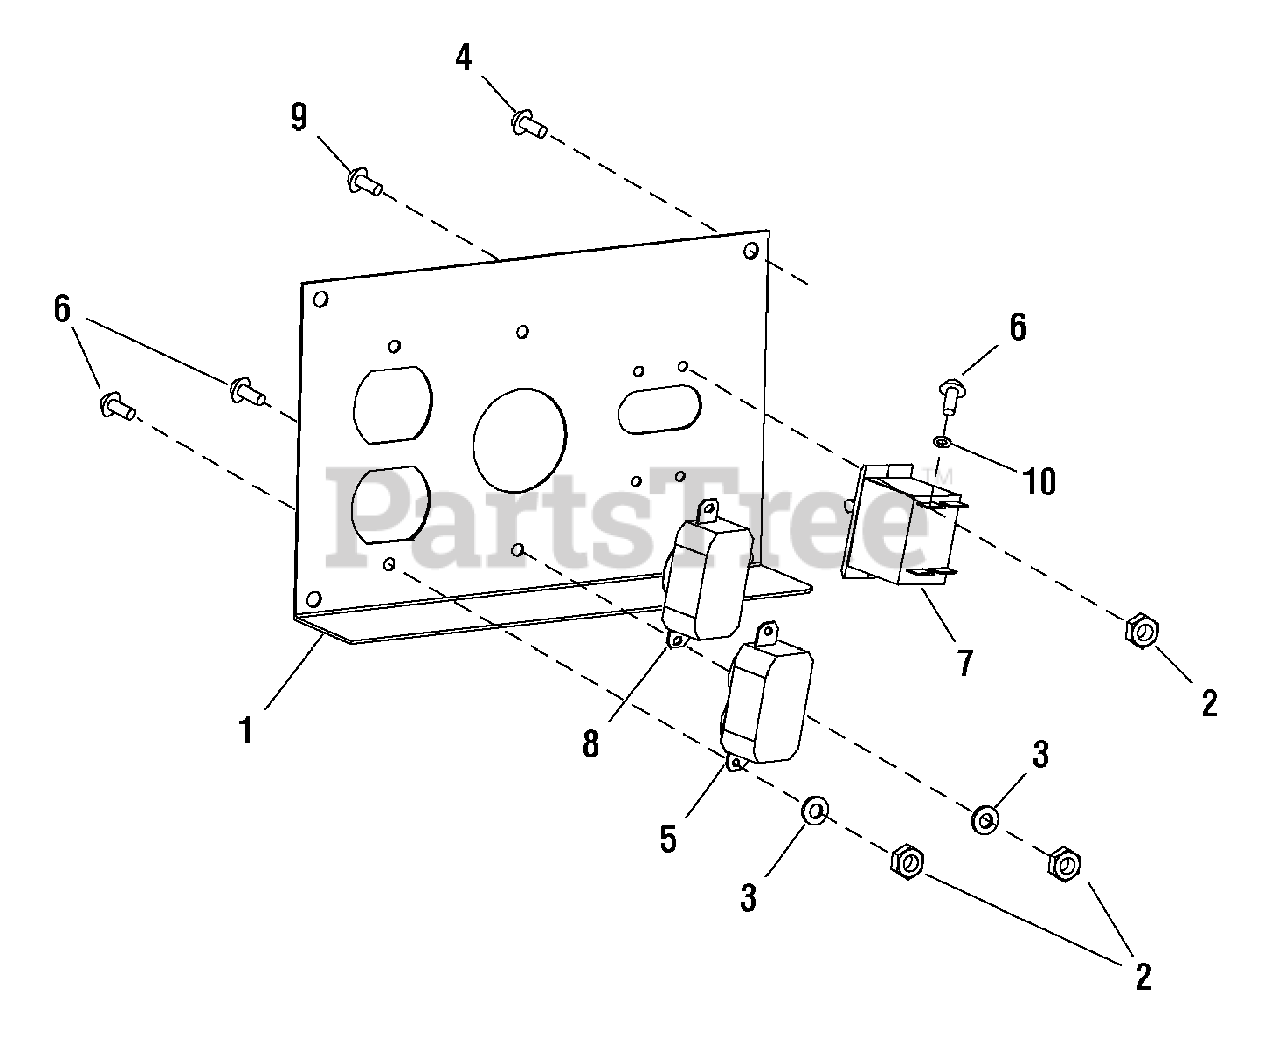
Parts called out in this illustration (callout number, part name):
1	CONTROL PANEL
2	* NUT, Nylon
3	* WASHER, M4 x 08
4	* SCREW, M6 x 16
5	OUTLET, 120/125V, 15/20a, Duplex
6	* SCREW, Pan Head, M4 x 10
7	CIRCUIT BREAKER, 15A
8	OUTLET, 120/240V, 20a, Locking
9	* SCREW, M3 x 06
10	* WASHER, Lock
